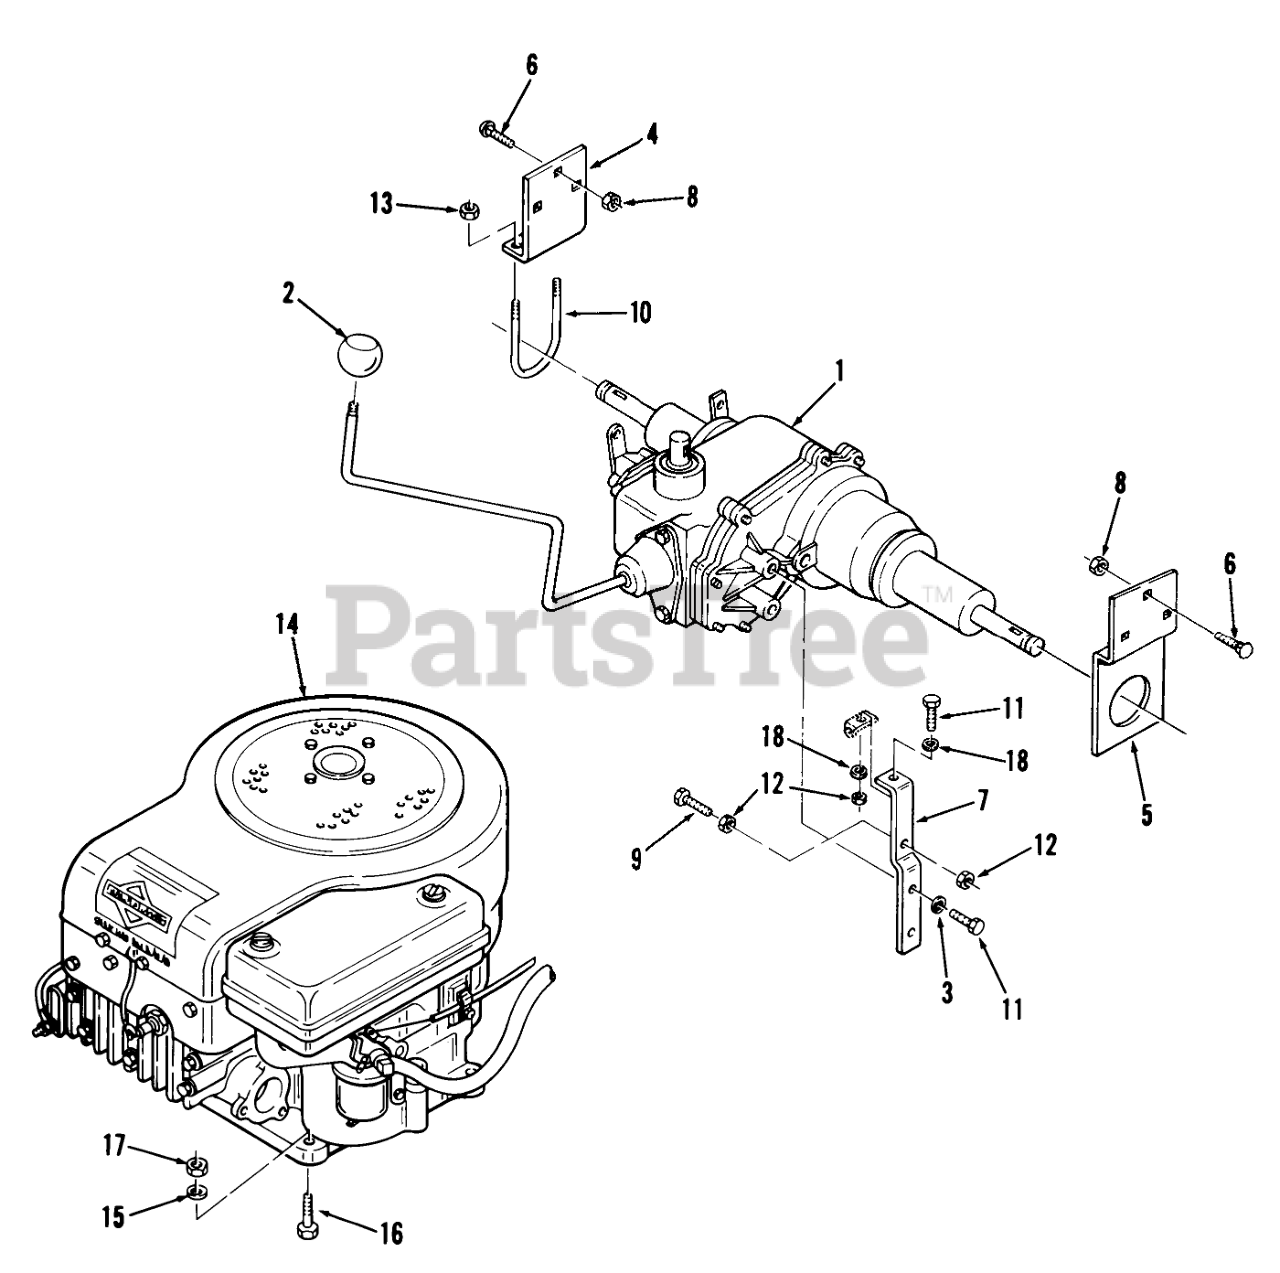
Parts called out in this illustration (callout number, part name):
1	Transmission-Peerless Mod. 669
2	SHIFT KNOB
3	Lockwasher
4	BRACKET-AXLE RH
5	BRACKET-AXLE LH
6	CARRIAGE BOLT -4
7	Bracket Trans. Mounting
8	Nut
9	Bolt 5/16-18 x 2
10	"U" Bolt Axle Mount
11	Bolt
12	Nut
13	Nut
14	Engine-8HP-B&S Model 191707, Type 1136-01
14	Engine-11HP-B&S Model 252707, Type 0151-01
15	WASHER 5/16 SAE
16	Bolt
17	Nut
18	WASHER 5/16 SAE
